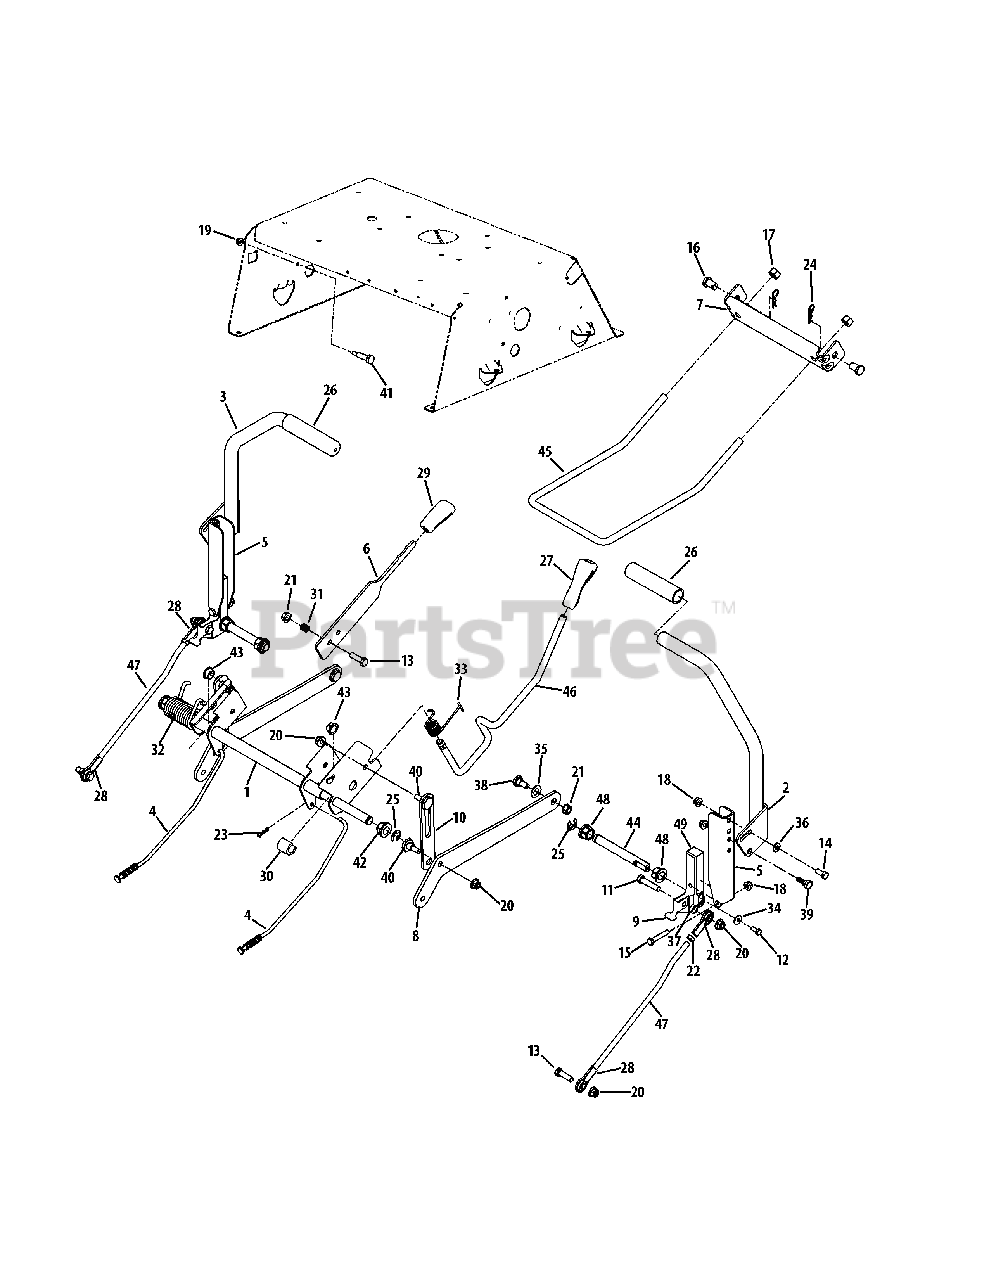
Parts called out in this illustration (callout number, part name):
1	Deck Lift Shift Assembly
2	RH Lapbar Lever Assembly
3	LH Labpar Lever Assembly
4	Brake Rod Assembly
5	Lapbar Pivot Bracket
6	Brake/Shabs Assembly
7	Front Deck Hanger Bracket
8	Deck Lift Arm Plate
9	Switch Actuator Bracket
10	Lift Link Plate
11	Hex Screw, 3/8-16 x 1.75
12	Hex Screw, 1/4-20 x .625
13	Hex Screw, 3/8-16 x 1.25
14	Hex Screw, 5/16-18 x .75
15	Hex Screw, 5/16-18 x 1.75
16	Clevis Pin, .50 x .78
17	Flex Lock Nut, 1/2-13
18	Flange Lock Nut, 5/16-18
19	Flange Lock Nut, 1/4-20 (50" Deck)
20	Flange Lock Nut, 3/8-16
21	Hex Lock Nut, 3/8-16, Centerlock
22	Jam Nut, 3/8
23	Bow-Tie Cotter Pin
24	Cotter Pin, .080 x 1.5625
26	Lapbar Grip (TB)
27	Handle Grip, 1/2
29	Selector Handle
30	Spacer, .621 x 1.00
31	Compression Spring, .50 x .50
32	Torsion Spring, 1.191 x 2.78
33	Spring, Torsion RZT
34	Bell Washer, .265 x .75 x .062
35	Flat Washer, .510 x 1.00 x .060
36	Flat Washer, .344 x .688 x .065
37	Spacer, .380 x .625 x .265
38	Shoulder Bolt, 3/8-16 x .496 x .336
39	Shoulder Screw, 5/16 x .437 x .268
40	Shoulder Screw, .500 x .434
41	Shldr. Screw, .374 x 1.16 (50" Deck)
42	Hex Flange Bearing
43	Flange Bearing, .626 x .938 x .344
44	Shaft Control
45	Front Hanger Deck Lift Rod
46	Deck Lift Handle Rod
47	Lapbar Control Rod
48	Hex Flange Bearing, .629
49	Control Hub
